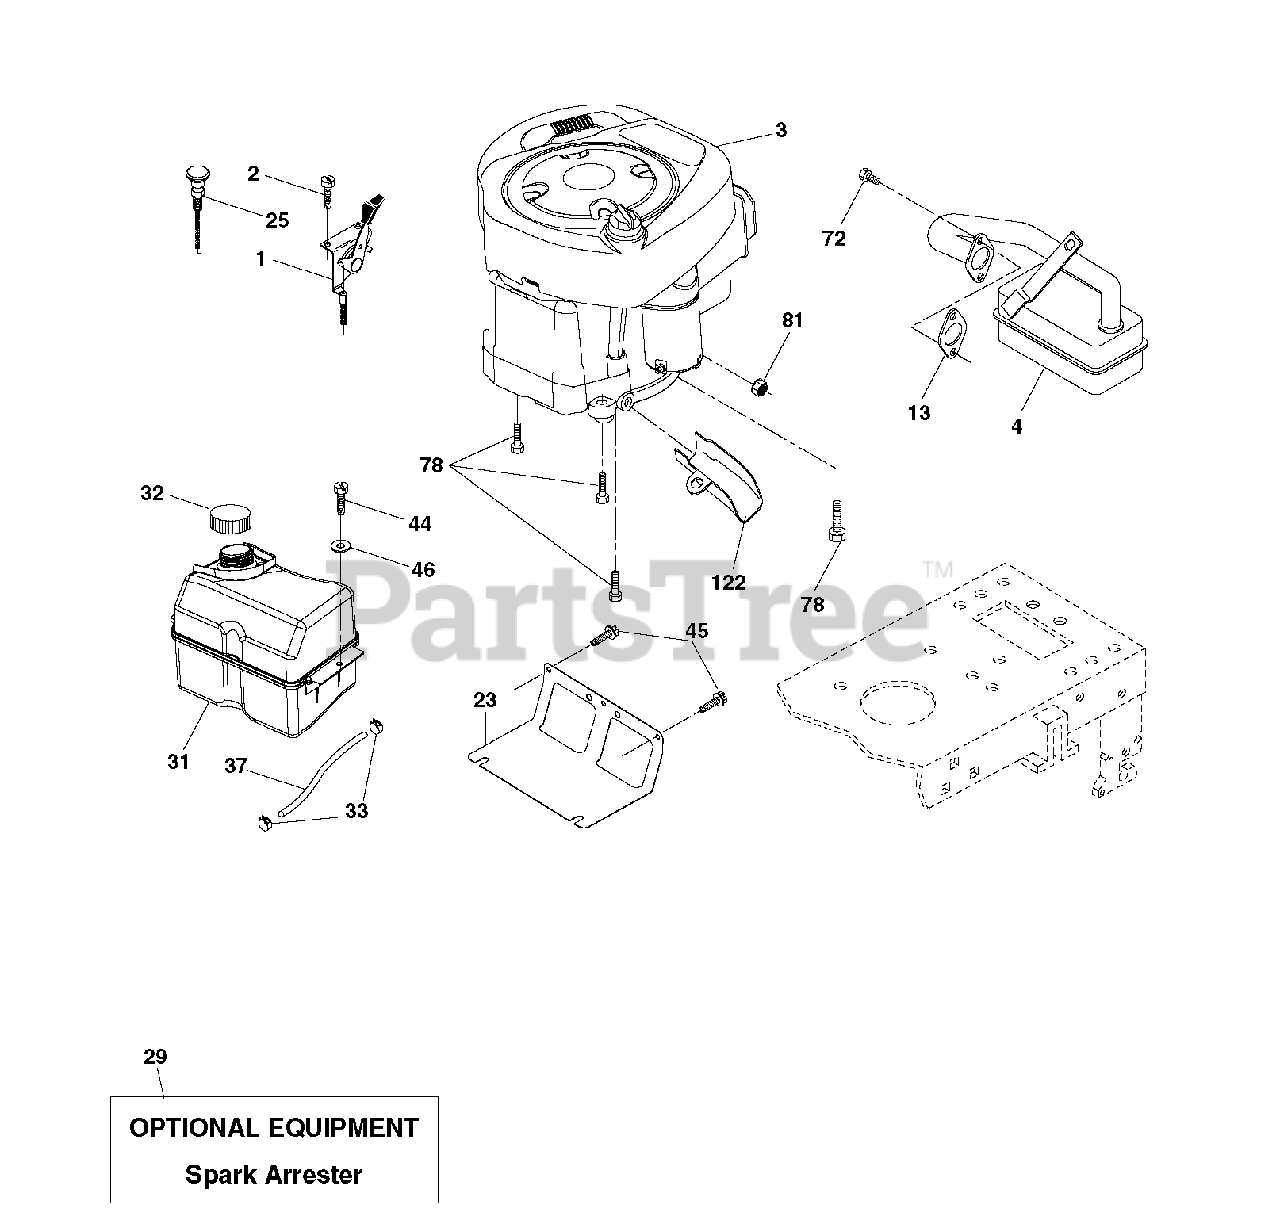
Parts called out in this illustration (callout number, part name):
1	CONTROL TH/CH FLAG
2	SCREW
13	REPL BY 532 27 22-93
23	SHEILD.BROWNING.DBR.GUARD
25	KNOB.ERGO.EXTENDED.RED (1 2)
29	ARRESTER SPARK (OPTIONAL)
32	CAP ASM.FUEL.2.25"FR.
44	SCREW HEXWSHR 1/4-20X3/4
45	SCREW, 3/8-16X3/4
72	SCREW.SOCKET HD.5/16-1
81	NUT
122	EXTENSION DRAIN OIL
